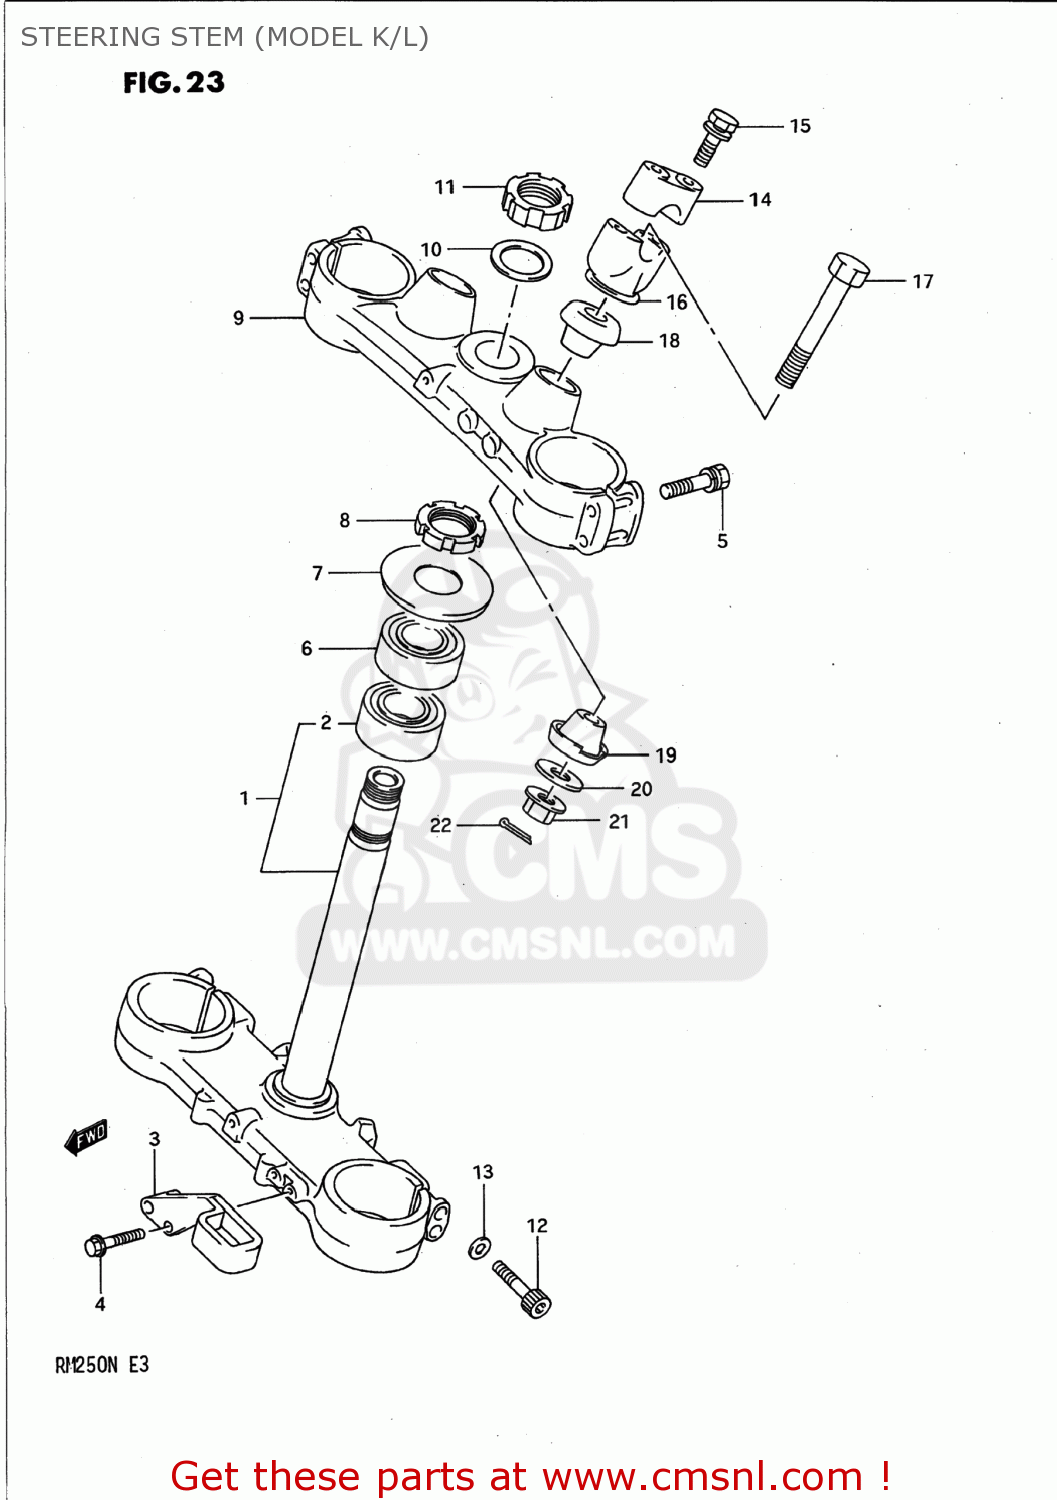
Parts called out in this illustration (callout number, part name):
1	STEM,STEERING
2	BEARING(28X54X16)
3	GUIDE,HOSE
4	BOLT
5	BOLT
6	BEARING
7	SEAL,STEERING,UPPER DUST
8	NUT,STEERING
9	HEAD,STEERING STEM
10	WASHER,STEERING STEM
11	NUT,STEM HEAD
12	BOLT
13	WASHER
14	HOLDER,HANDLEBAR
15	BOLT,HANDLE HOLDER
16	HOLDER,HANDLE LWR
17	BOLT
18	DAMPER,UPR
19	DAMPER,LWR
20	WASHER,HANDLEBAR HOLDER
21	NUT
22	COTTER PIN
